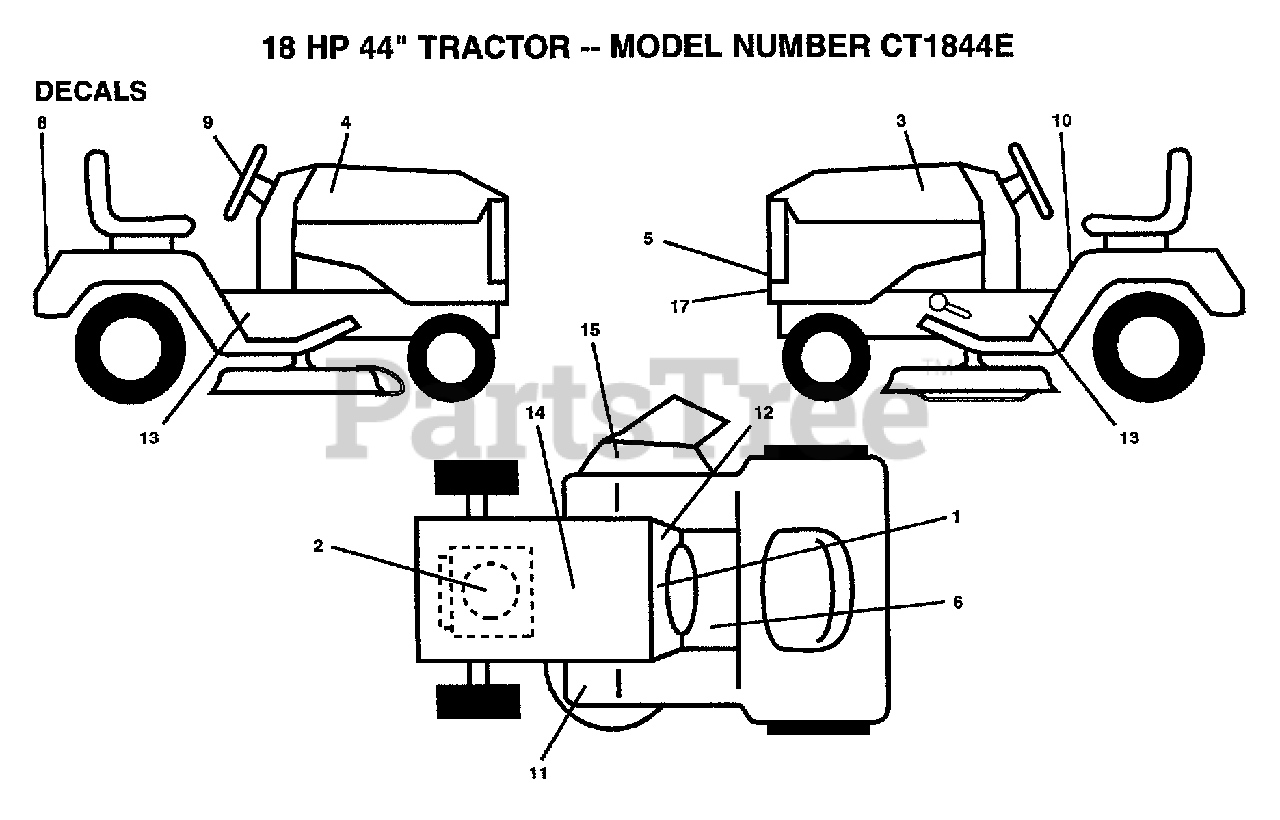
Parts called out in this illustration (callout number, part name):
2	DECAL.ENG.272559
3	DECAL.STRIPE.HOOD
5	GRILL DECAL
8	DECAL.FENDER
9	DECAL.STG.WHL.INS
10	DECAL CAUTION
11	DECAL T
14	DECAL
15	DECAL WARNING
17	DECAL.GRILLE
